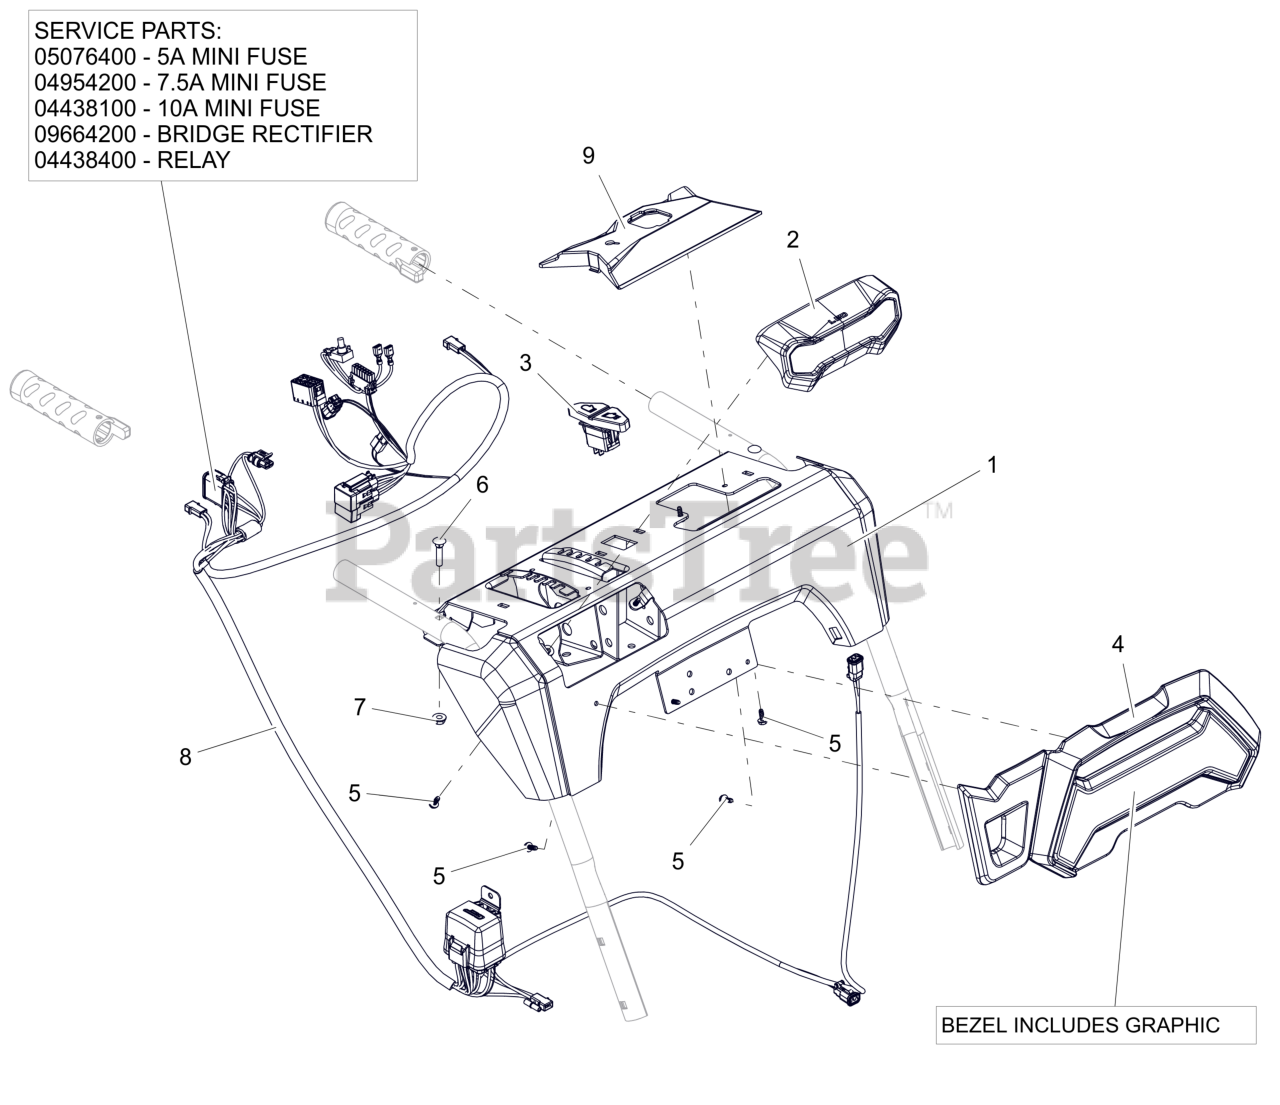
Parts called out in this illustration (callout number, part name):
1	PANEL, CONTROL-ECHUTE EFI W/SAFETY DECALS
2	HEADLIGHT ASM- LED
3	SWITCH- ROCKER SPST-ON/OFF
4	BEZEL- LARGE - PLATINUM
5	SCR, PLASTIC #10X.50
6	BLT-RDHDXLSQNK.25-20X1.25 G5ZC
7	NUT-LK-CTR-FLG .25-20 ZC120
8	HARNESS-WIRE- LT HG EFI ECHUTE
8	FUSE, 5 AMP MINI-ATC
8	FUSE, 7.5 AMP MINI-ATC
8	FUSE,10 AMP MINI-ATC
8	RECTIFIER, BRIDGE
8	RELAY,MICRO5 TERML W/RESISTOR
9	BEZEL, OPERATOR EFI DECAL
